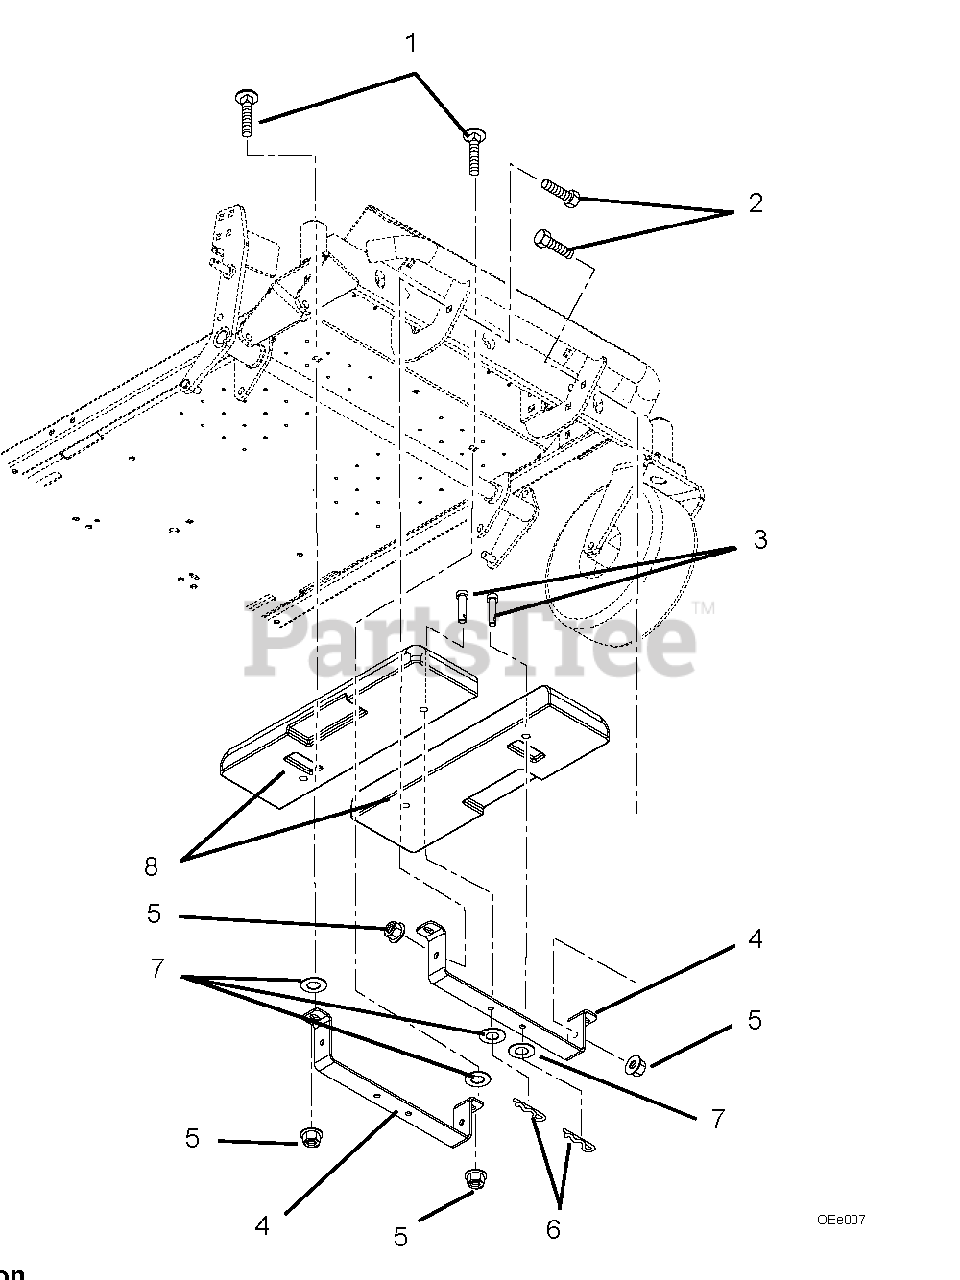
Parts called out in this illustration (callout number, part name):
1	Bolt, Round Head Square Neck .38-16 x 1.00 Grade 5
2	Bolt, Hex .38-16 x 1.00 Grade 5
3	Pin, Clevis .494 x 2.50
4	Bracket, Weight
5	Nut, Locking-Top-Flange .38-16
6	Pin, Hair-External .12 x .31 x 2.37
7	Washer, Flat-Steel .515 x 1.625 x .250
8	Counterweight
